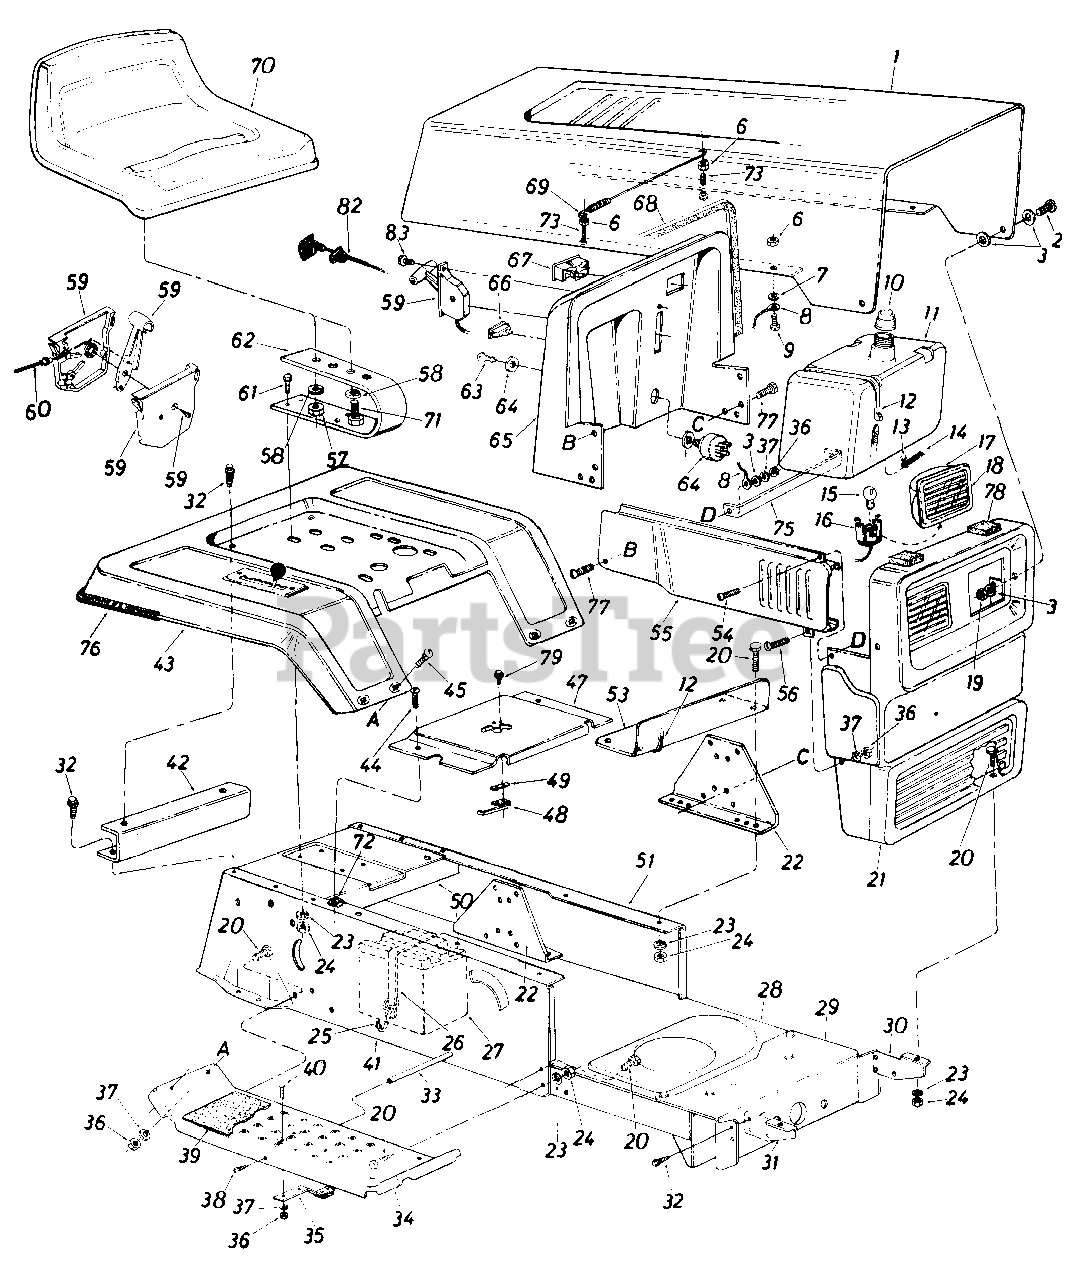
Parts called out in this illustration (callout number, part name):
1	Hood
2	Hex Scr. 1/4-20 x .62" Lg.*
3	Fl-Wash. .296" I.D. x .73" O.D.
6	Hex Sems Nut #10-24 Thd.*
7	Fl-Wash. .203" I.D. x .41" O.D. x .040
8	Hood Stop
9	Truss Hd. Scr. #10-24 x 1/2"*
10	Fuel Cap Gauge
11	Fuel Tank
12	Tie Strap
13	Hose Clamp
14	Fuel Line
15	Lamp
16	Twist Lock-Lamp Socket
17	Headlight Housing
18	Lens
19	Hex L-Nut 1/4-20 Thd.
20	Hex Bolt 5/16-18 x .75" Lg.*
21	Grille
22	Dash Support Bracket
23	L-Wash. 5/16" I.D.*
24	Hex Nut 5/16-18 Thd.*
25	Battery Strap Hook
26	Battery Hold Down Strap
27	12V Battery
28	Lower Frame
29	Front Pivot Brk't.
30	Grille Mount Brk't.-L.H.
33	Running Board Rod
34	Running Board
35	Blade Brake Ass'y.
36	Hex Nut 1/4-20 Thd.*
37	L-Wash. 1/4" I.D.*
38	Truss Mach. Scr. 5/16-18 x .75" Lg.*
39	Foot Pad
40	Carriage Bolt 1/4-20 x .62"*
41	R.H. Side Frame
42	Fender Mount Brace
43	Rear Fender
45	Carriage Bolt 1/4-20 x .50"*
47	Transmission Panel
48	Reverse Safety Switch
49	Insulator Nut Plate
50	Hitch Plate
51	L.H. Side Frame
53	Fuel Tank Support
54	Truss Hd. Scr. 1/4-20 x .75" Lg.*
55	Side Cover-R.H.
56	Truss Mach. Scr. 1/4-20 x .50" Lg.*
57	Hex Nut 1/2-13 Thd*
58	L-Wash. 1/2" I.D.*
59	Throttle Control Box Ass'y.
60	Throttle Control Wire
61	Hex Bolt 5/16-18 x 1.0"*
62	Seat Spring 5.5" High
63	Ignition Key
64	Ignition Switch
65	Dash Panel
66	Light Switch
67	Ammeter
68	Trim Strip-27"
69	Hood Spring
70	Seat Ass'y.
71	Hex Bolt 1/2-13 x 1.0" Lg.
72	Speed Nut #10Z
73	Hex Scr. #10-24 x 1.0" Lg.
75	Tie Strap-Grille/Side Panel
76	Trim Strip-81"
77	Hex Wash. Hd. Tap Scr. 1/4 x .751' Lg.
78	Foam Strip 3/8 x 1-1/8" x 1'/2" Lg.
79	Hex Wash. Hd. AB-Tap #8 x .50" Lg.
82	Choke Control 29" Lg.
83	Truss Mach. AB-Tap Scr. #10 x .5" Lg.
